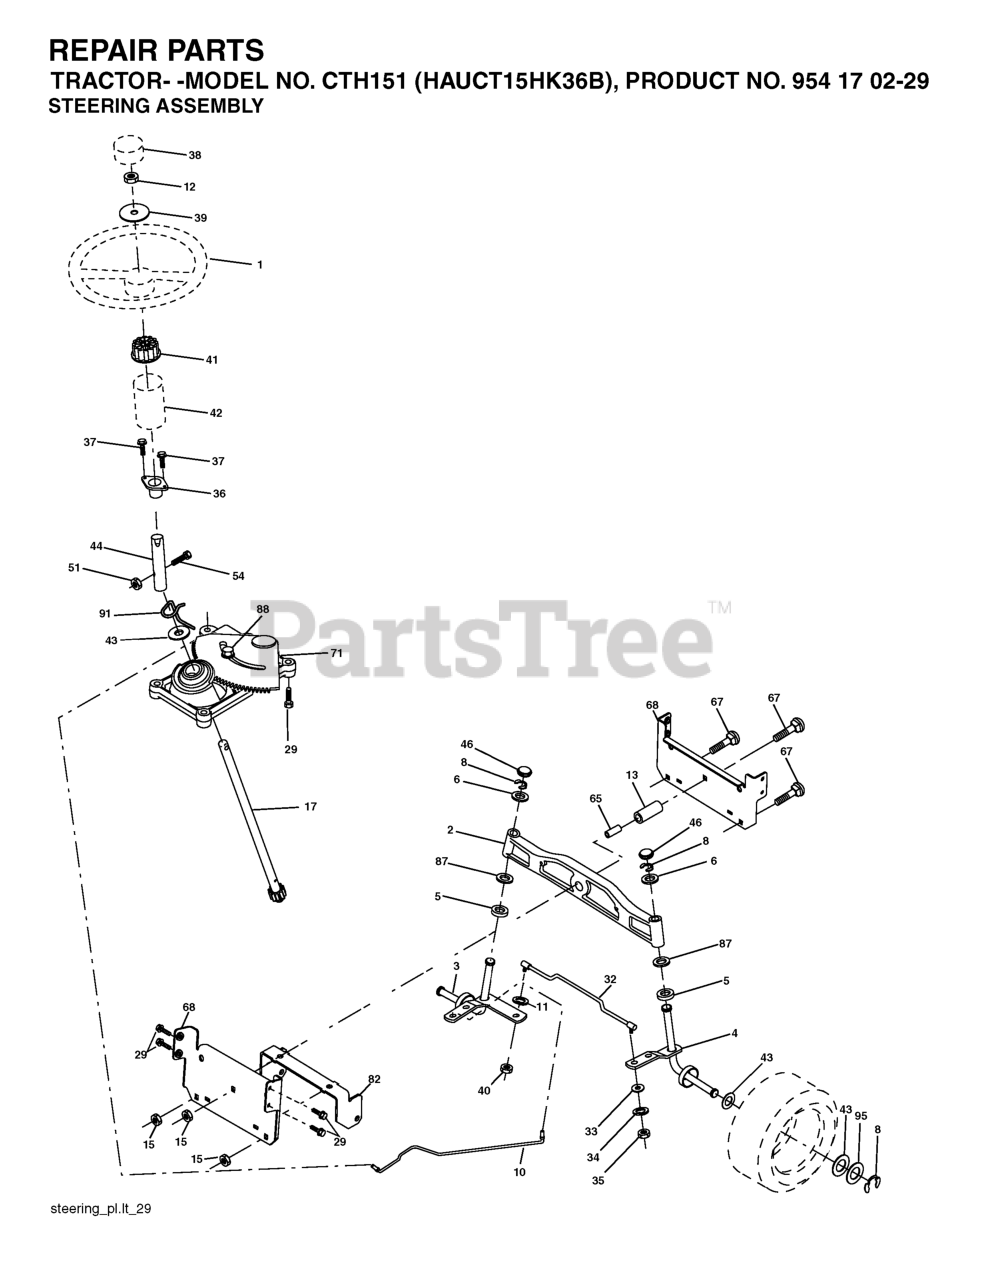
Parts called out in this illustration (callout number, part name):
1	STEERING WHEEL
2	AXLE ASSY FRONT
3	SPINDLE.ASM.LH.15"TIRES
4	SPINDLE.ASM.RH.15"TIRES
5	THRUST WASHER
10	DRAGLINK.15".TIRES.2001
11	WASHER, LOCK 3/8
12	NUT.HEX.1/2-20
13	TUBE, PIVOT AXLE
15	NUT
17	SHAFT ASM, STEERING
29	SCREW, 3/8-16X3/4
32	ROD.ASM.TIE.BALL.JOINT.NOVAN
33	WASHER M
34	WASHER.LOCK.HVY.HLCL.SPR.5/16
35	NUT, CROWNLOCK
36	BUSHING, STEERING
37	SCREW.TT.#10-32X.5.3/8.FLANGE
38	CAP.WHEEL.STEERING.GREY
39	Washer 9/16 ID x 1 1/2 OD 11 Ga. Zin
40	NUT CROWNLOCK 3/8-24
41	STEERING WHEEL ADAPTOR
42	BOOT STEERING
44	EXT, STEERING SHAFT
46	CAP.SPINDLE.BLACK
51	NUT.CROWNLOCK.1/4-28
54	Bolt Hex 1/4-28 unf x 1-1/4 Gr. 8
65	SPACER BRACE AXLE
67	BOLT CARRIAGE
68	BRACE.AXLE.15"TIRES
71	STEERING ASM
82	BRACKET
87	WASHER, FLAT .781 X 1 1/2"
88	BOLT, SHOULDER 7/16-20
91	CLIP.STEERING
95	WASHER.HARDENED
